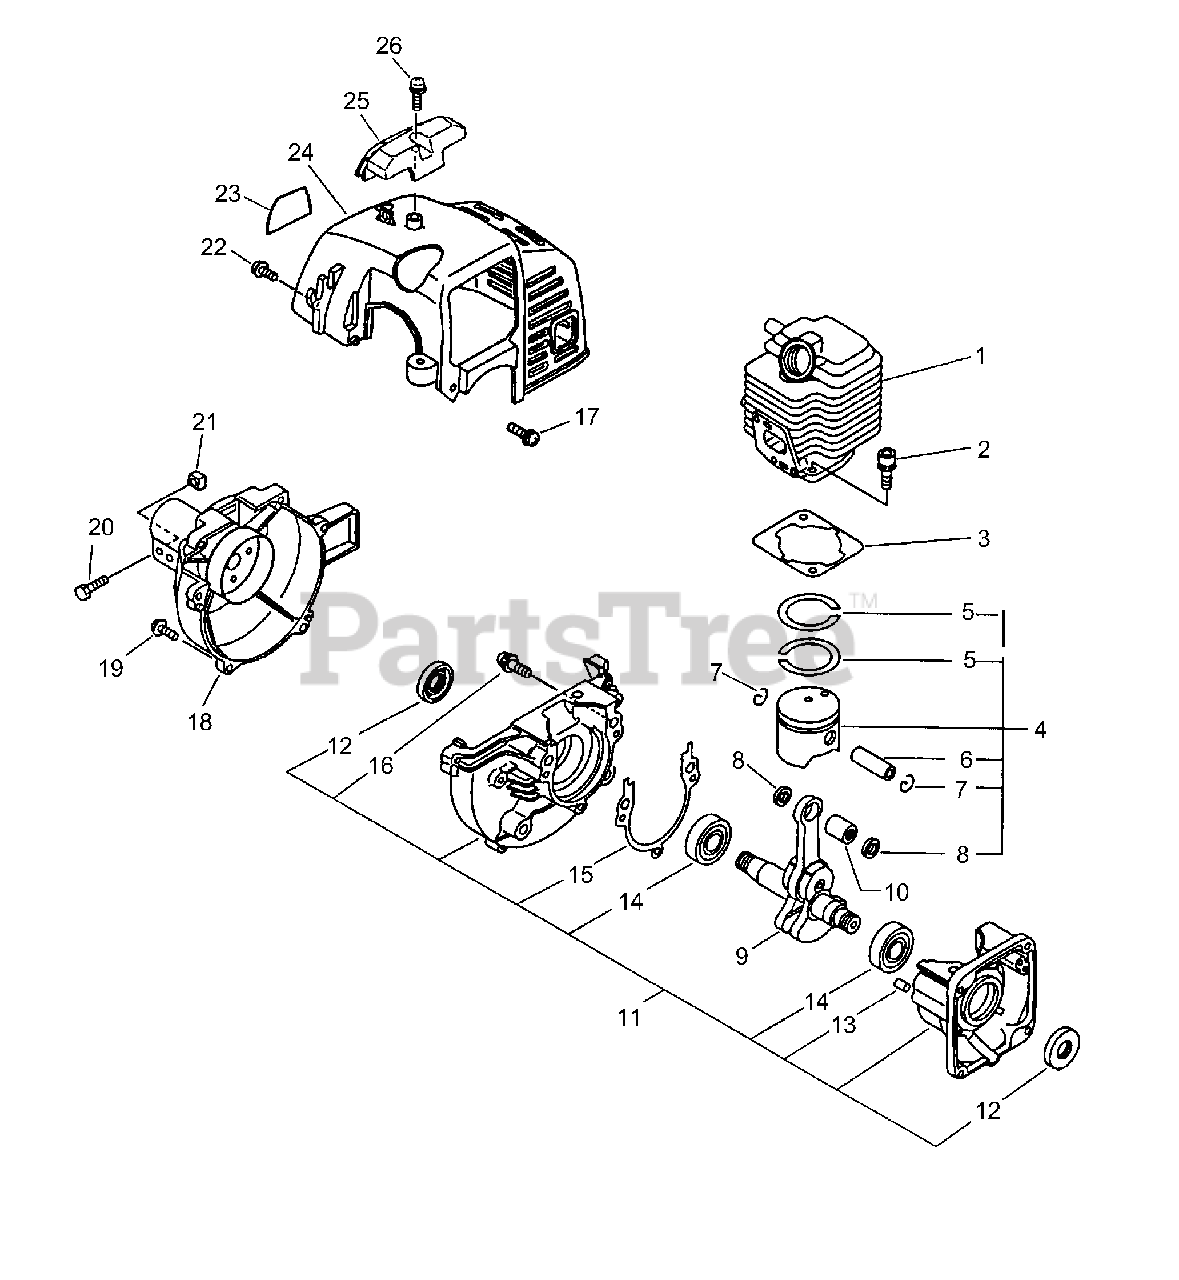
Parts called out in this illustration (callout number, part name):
1	CYLINDER
2	SCREW - 5X22
3	GASKET, CYLINDER
4	PISTON KIT
5	RING, PISTON
6	PIN, PISTON
7	RING, RETAINING
8	SPACER, PISTON
9	CRANKSHAFT ASSY
10	BEARING, NEEDLE
11	CRANKCASE KIT
12	SEAL, OIL
13	PIN - LOCATING
14	BEARING, BALL - 6201
15	GASKET, CRANKCASE
16	SCREW - 5X28
17	SCREW - 4X12 -- TAPPING
18	FAN CASE ASSY
19	SCREW - 4X18
20	BOLT - 5X28
21	NUT - 5 -- SQUARE
22	SCREW - 4X16
23	LABEL - MODEL SHC-1700
24	COVER, ENGINE - GRAY
25	GUARD, TOP - GRAY
26	SCREW - 5X16 -- TAPPING
